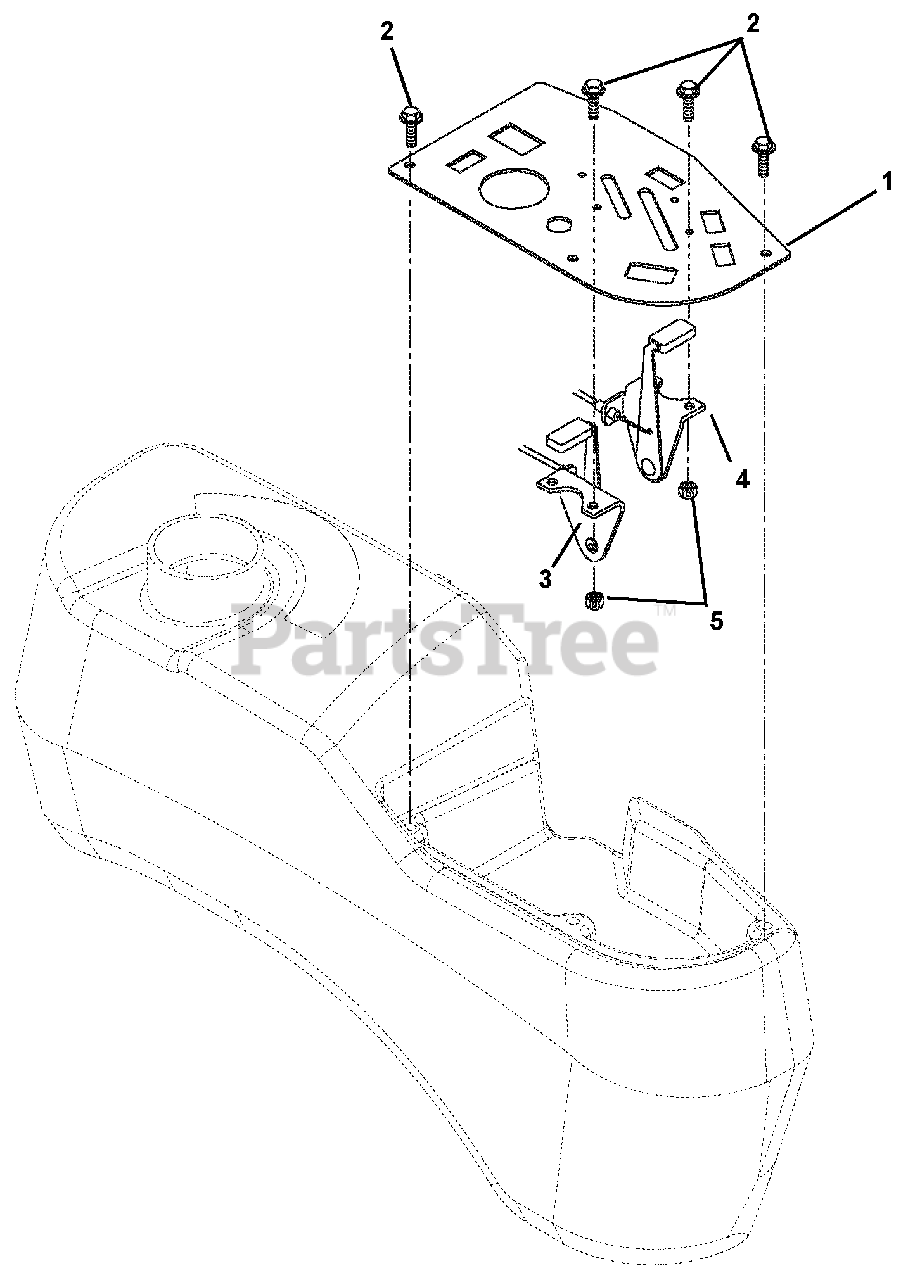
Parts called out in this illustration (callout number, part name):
1	Panel, Control
2	Screw, Machine 10-24 x .50 Hex Washer Head (045, 046, 047, 052, 066, 067, 068, 072, 087,
3	Throttle, Control
4	Choke Control
5	Nut, Locking Nylon 10-24 With Insert
